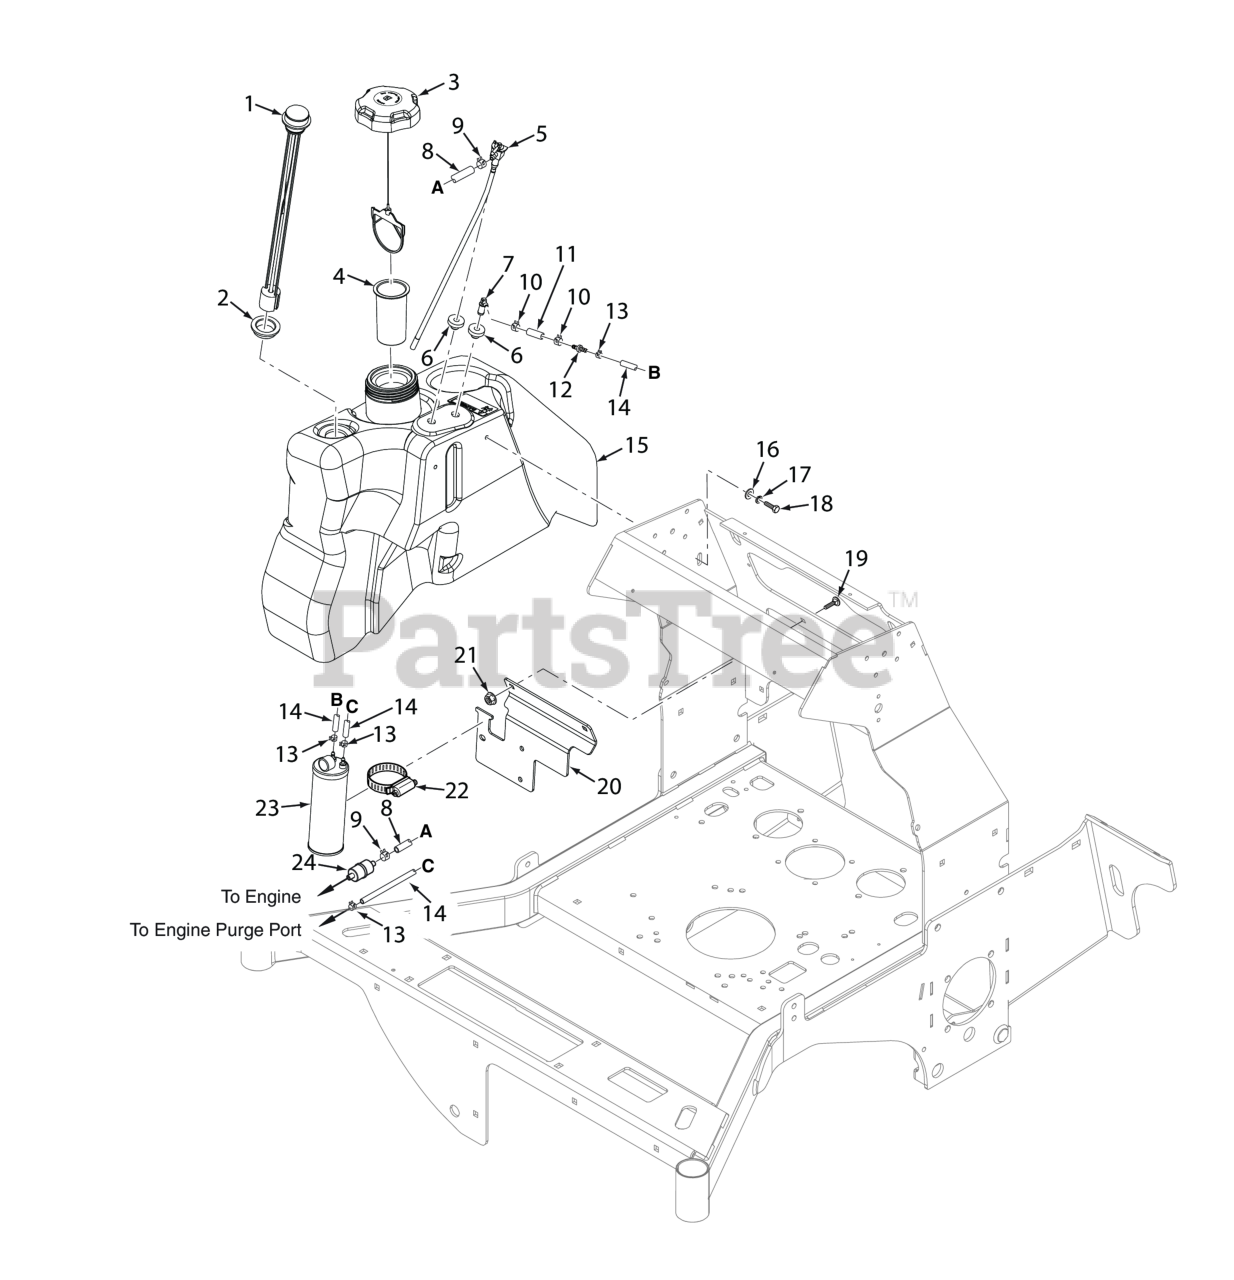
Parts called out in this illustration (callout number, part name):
1	Fuel Gauge Assy., 16-1/2"
2	Grommet, Fuel Gauge
3	Fuel Cap w/ Tether (E.P.A.)
4	Tube, Fuel Tank Insert - 4"
5	Valve, Fuel Shut Off
6	Bushing, 0.56" Dia. Viton
7	Remote Vent, With No Valve
8	Fuel Hose, 1/4" I.D. Non-Perm (791DFI Fuel Return) - Order by Inch
9	Clamp, Fuel Hose 1/4" Hose I.D.
10	CLAMP, FUEL HOSE(KAWASAKI ONLY)
11	Hose, 1/4" Vapor Recovery (order by inch)
12	Mender, 1/4 x 3/16 w/0.02 Hole
13	Clamp, Vapor Recovery Hose 3/16"
14	Hose, Vapor Recovery 3/16" (order by inch)
15	Fuel Tank Assy., Windstorm (Incl. #1,2,5,6,7)
16	Flatwasher, 5/16-.375 x .875 x .083 (35BV & 37BV-EFI)
17	Lockwasher, 5/16 (.317 x .586 x .078) Helical Spring
18	BOLT, SERRATED FLANGE HEX HEAD 5/16-18 X 3/4"
19	Bolt, 5/16-18 x .75 RHSN Carriage
20	Bracket, Hydro Tank Mounting
21	Nut, Serrated Flange 5/16-18 (Right Front Engine Mounting, Briggs and Kohler Only)
22	Clamp, 3-1/2" Max. Dia.
23	Carbon Canister - SVR-52V / SVR-61V
24	Dust Filter, Carbon Canister
